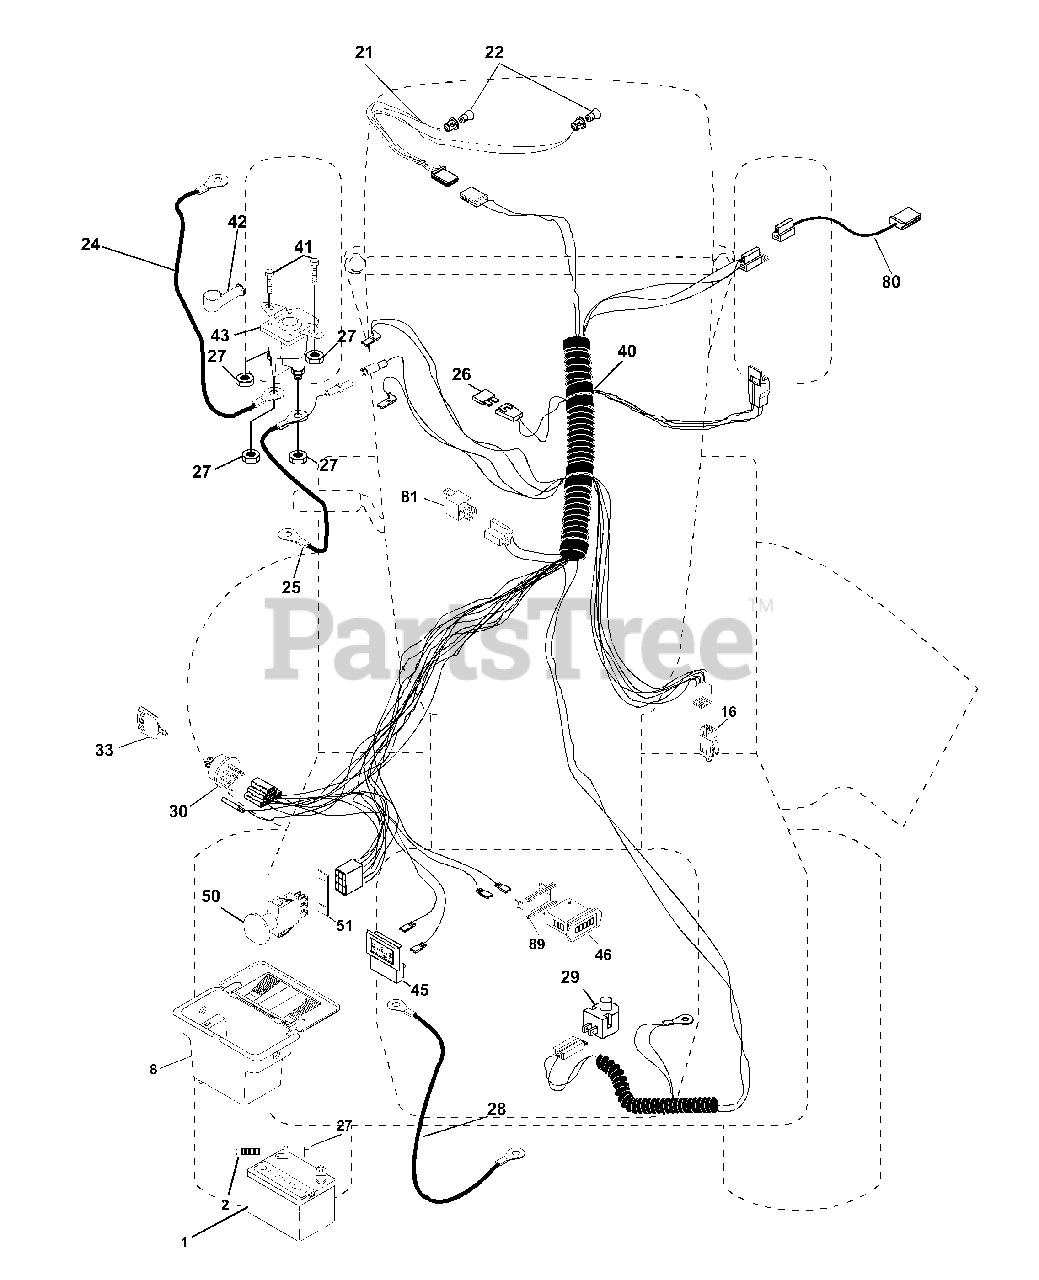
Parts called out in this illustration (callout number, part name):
1	Battery 12 Volt 25 AMP
2	Bolt Hex Hd 1/4-20unc X 3/4
8	Case Battery Mech Hinge
16	Switch Interlock Push-In
21	Harness Asm Light W/4152j
22	Bulb Light #1156
24	Cable Battery 6 Ga 11" red
25	Cable Battery 6 Ga 44" red w/16 wire
27	Nut Keps Hex 1/4-20 Unc
28	Cable Ground 6 Ga 12" black
29	Switch Plunger Nc Gray
30	Switch Ign
33	Key Ign Generic
40	Harness Ign.
41	Bolt Blk Fin Hex 1/4 - 20 x 1/2
42	Cover Terminal Red
43	Solenoid
45	Ammeter Rectangular 15 Amp
46	Meter Hour
50	Switch PTO
51	Ring Retainer PTO
80	Harness Clutch Evx
81	Relay Asm.
89	Bracket Snap-In Hourmeter
